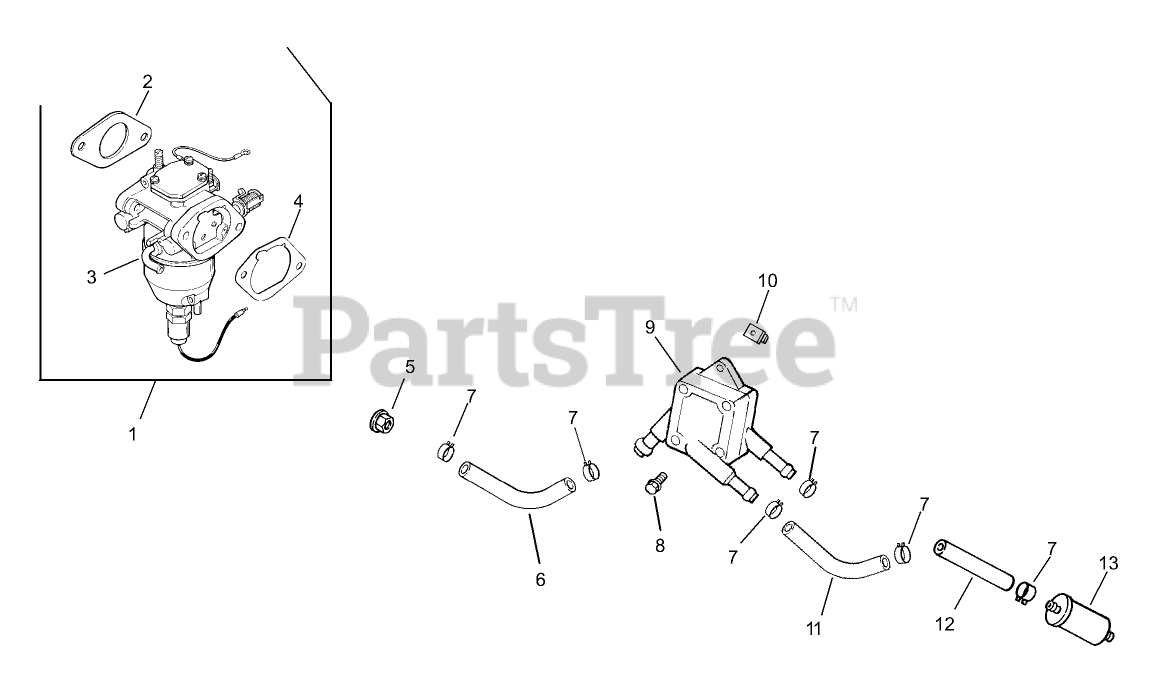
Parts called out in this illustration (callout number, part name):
1	Kit, carburetor w/gaskets (Includes 2-4)
2	Gasket-carburetor
3	Carburetor assembly (For information only not available separately)(Service with kits 24 757 36-S and 24 757 38-S)
4	GASKET-BASE, AIR CLEANER
5	NUT-FLANGE (M6X1.0)
6	Line, fuel 12"
7	CLAMP-HOSE, SPRING (1/2)
8	SCREW-TAP (M6X1.7X18)
9	PUMP-FUEL
10	Nut-Plastic
11	Line, fuel 10-1/2
12	Line-Fuel (9.5)
13.	Filter, fuel
